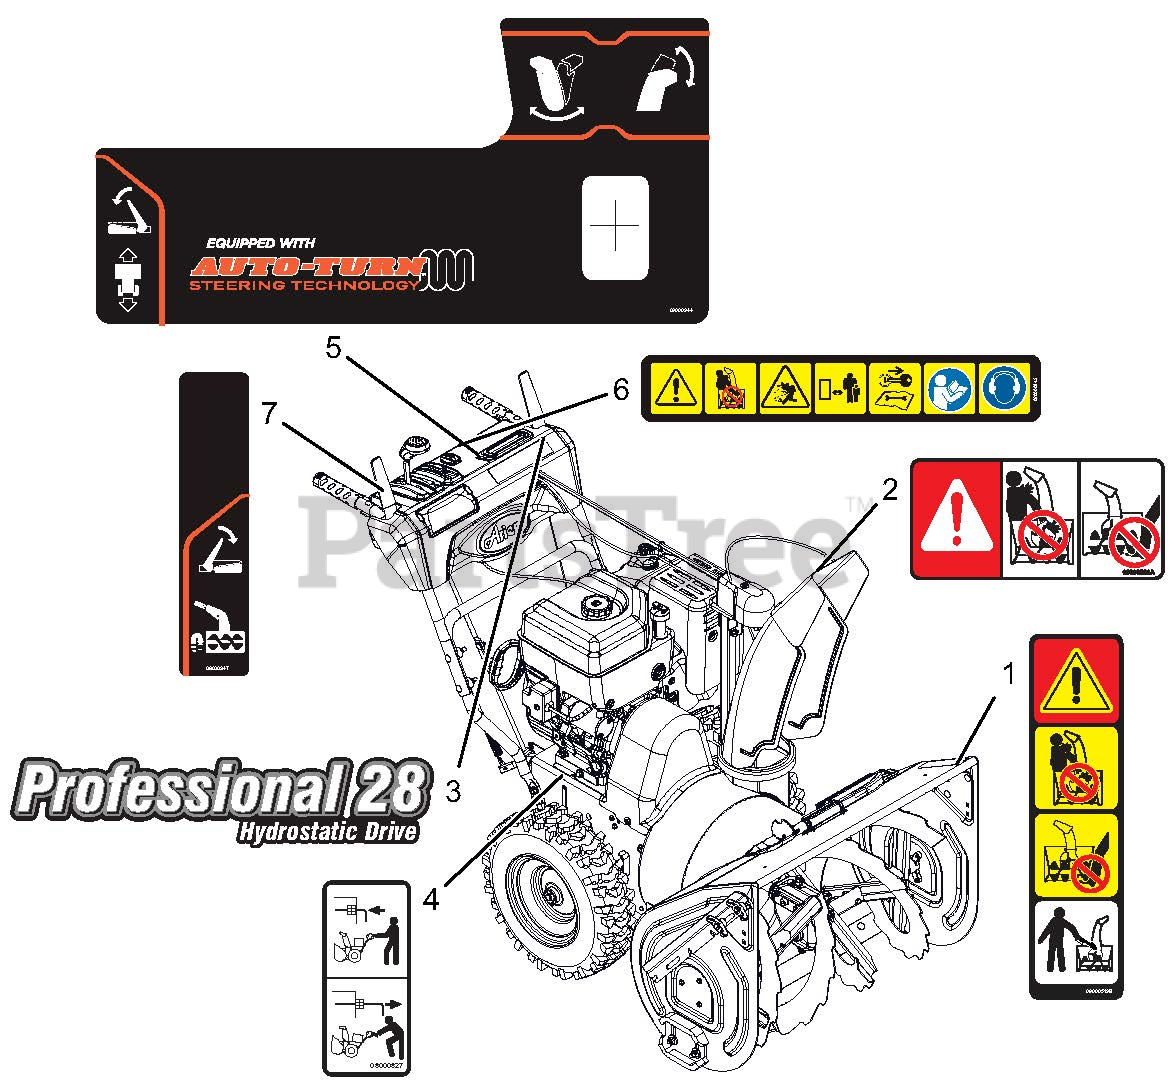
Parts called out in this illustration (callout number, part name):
1	DECAL, DANGER - ROTATING PARTS
2	DECAL, DANGER
3	DECAL, PRO HYDRO 28 DASH
4	DECAL, BYPASS
5	DECAL,CONTROL-LG QT2
6	DECAL,DASH - SAFETY
7	DECAL,CONTROL-RH CONTROL
